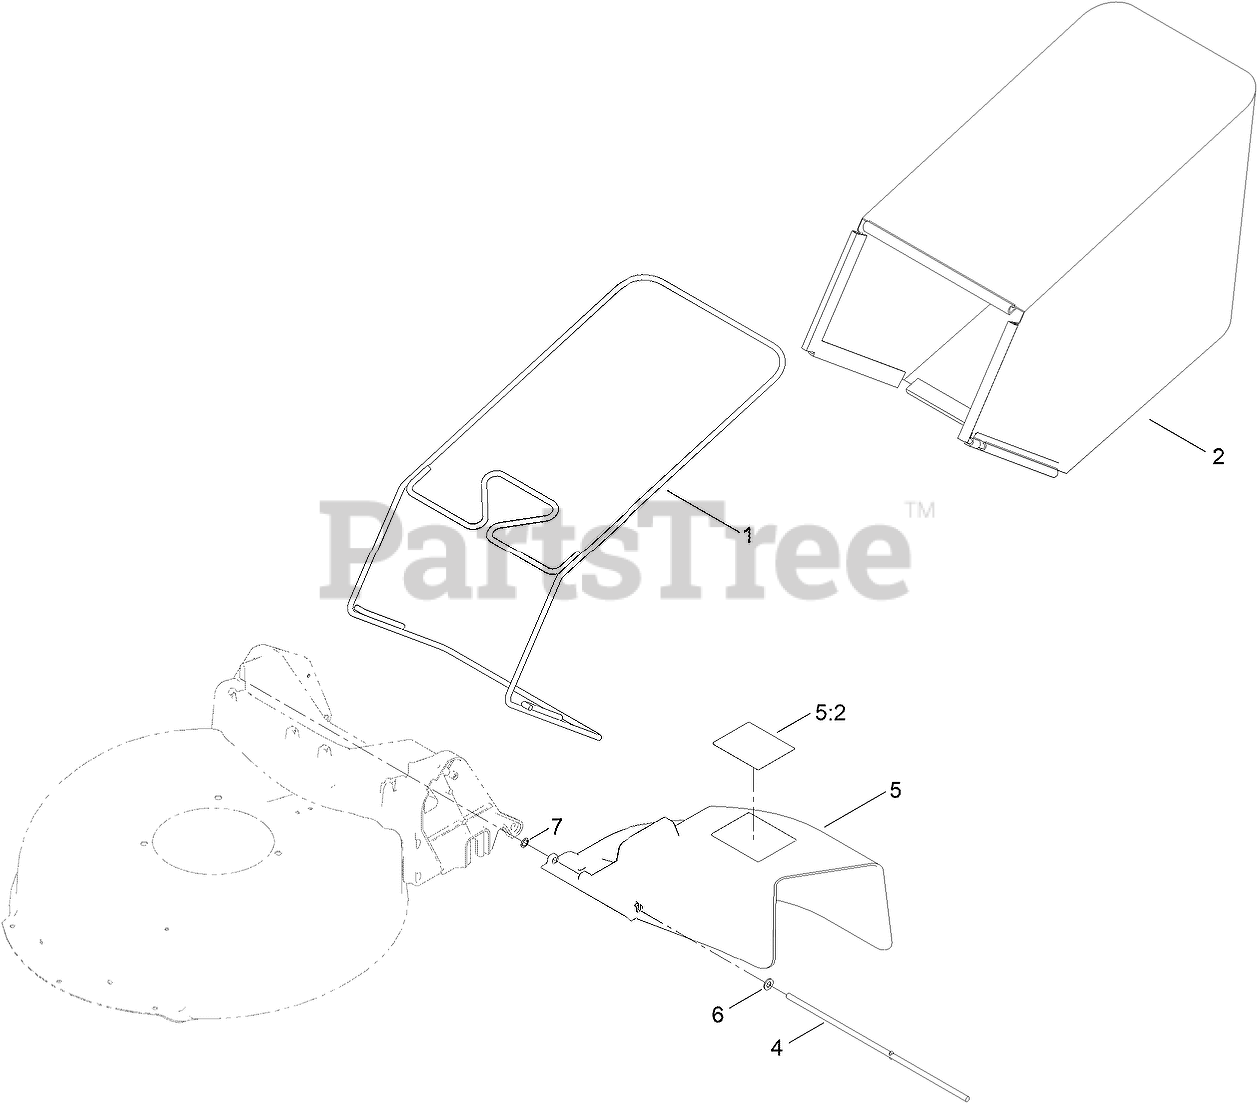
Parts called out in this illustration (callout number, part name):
1	FRAME-BAG
2	GRASS BAG ASM
5	DEFLECTOR-CHUTE
5:2	DECAL-WARNING
6	WASHER-PLAIN
7	RING-RETAINING
